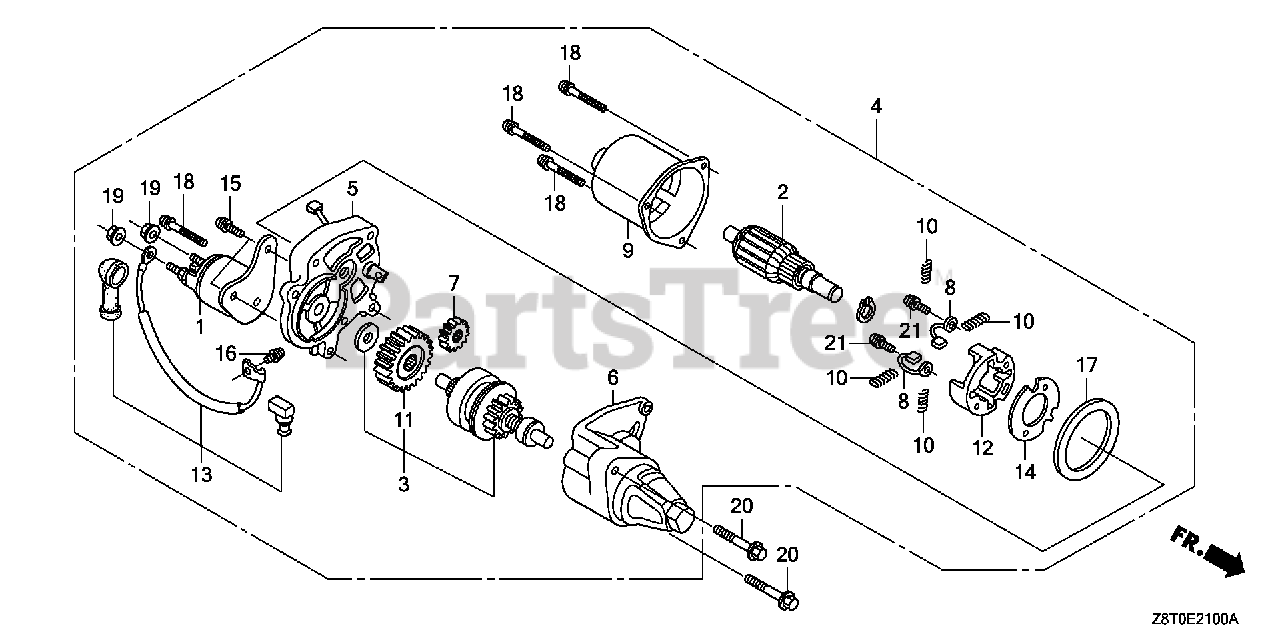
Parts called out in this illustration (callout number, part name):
1	CONTACTOR ASSY.
2	ARMATURE
3	CLUTCH, OVERRUNNING
4	STARTER MOTOR UNIT
5	BRACKET, CENTER
6	BRACKET, FR.
7	GEAR, DRIVE PINION
8	BRUSH
9	YOKE
10	SPRING, BRUSH RETURN
11	GEAR, REDUCTION
12	HOLDER, BRUSH
13	WIRE, WATER COVER
14	INSULATOR
15	BOLT-WASHER (5X14)
16	SCREW-WASHER (4X6)
17	GASKET
18	SCREW-WASHER (5X3)
19	NUT-WASHER (6MM)
20	BOLT, FLANGE (8X35)
21	SCREW-WASHER (4X14)
